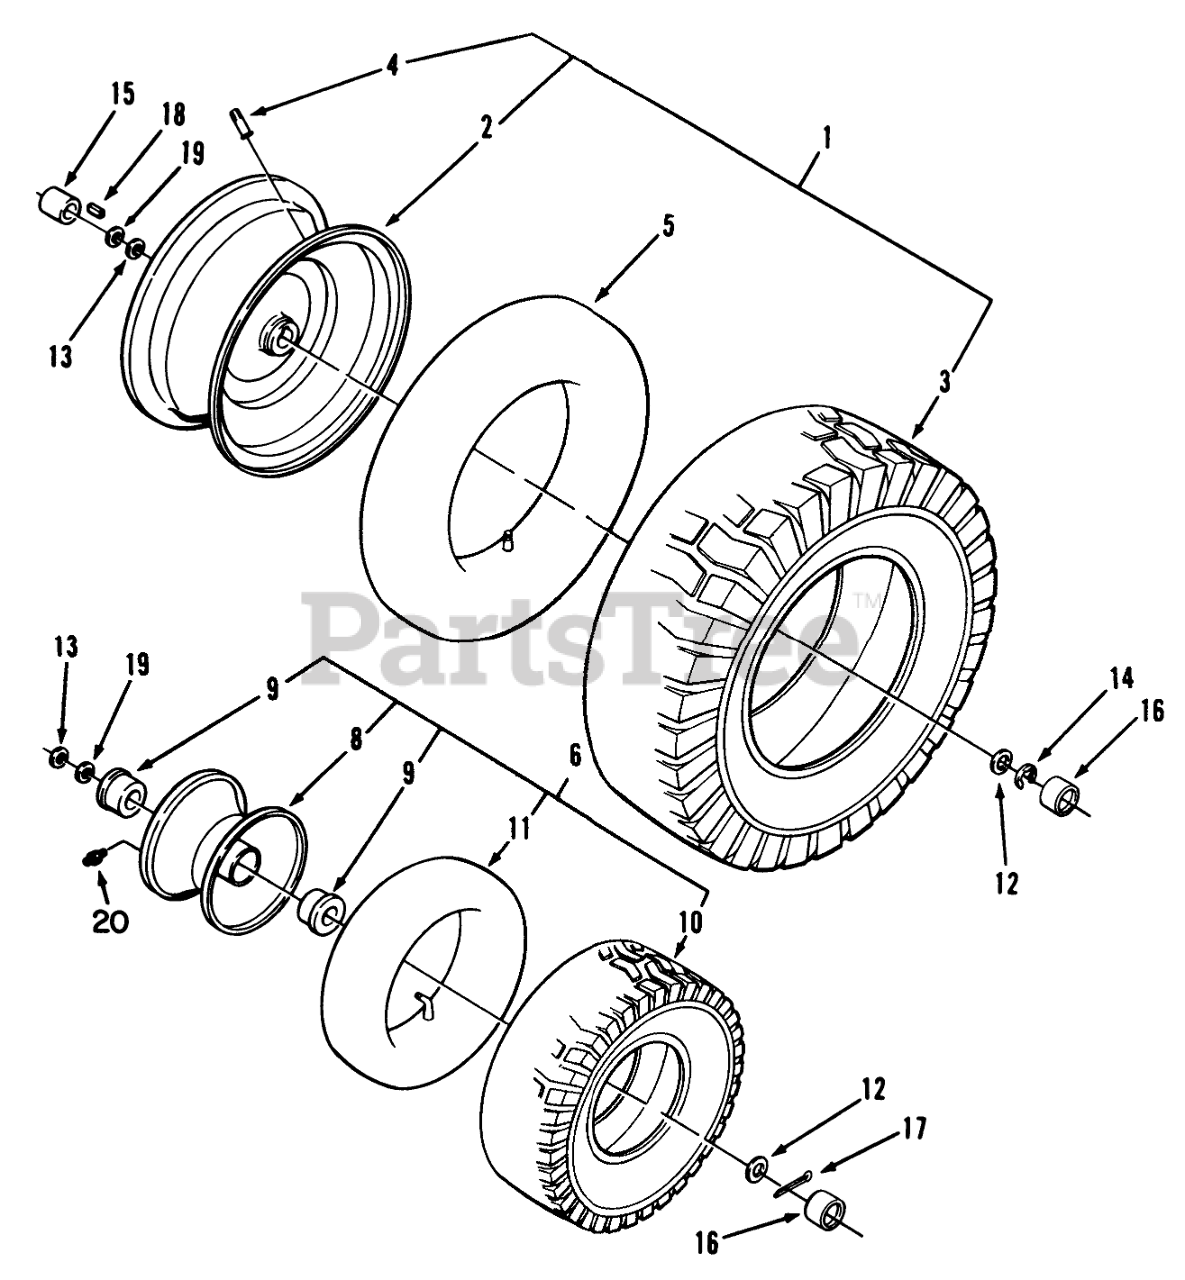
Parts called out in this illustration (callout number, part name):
1	ASSY WHEEL & TIRE
2	ASSY WHEEL
3	TIRE TURF SAVER 16X6.50-8
4	VALVE
5	TUBE-INNER
6	ASSY-WHEEL & TIRE
8	ASS'Y-WHEEL
9	BUSHING
10	TIRE TURF SAVER FT
12	WASHER-FLAT
13	WASHER
14	E-RING
15	LH AXLE SPACER
16	HUB CAP-FLAT BLACK
17	PIN-COTTER
18	SQ KEY
19	WASHER-SHIM
20	ZERK-GREASE
